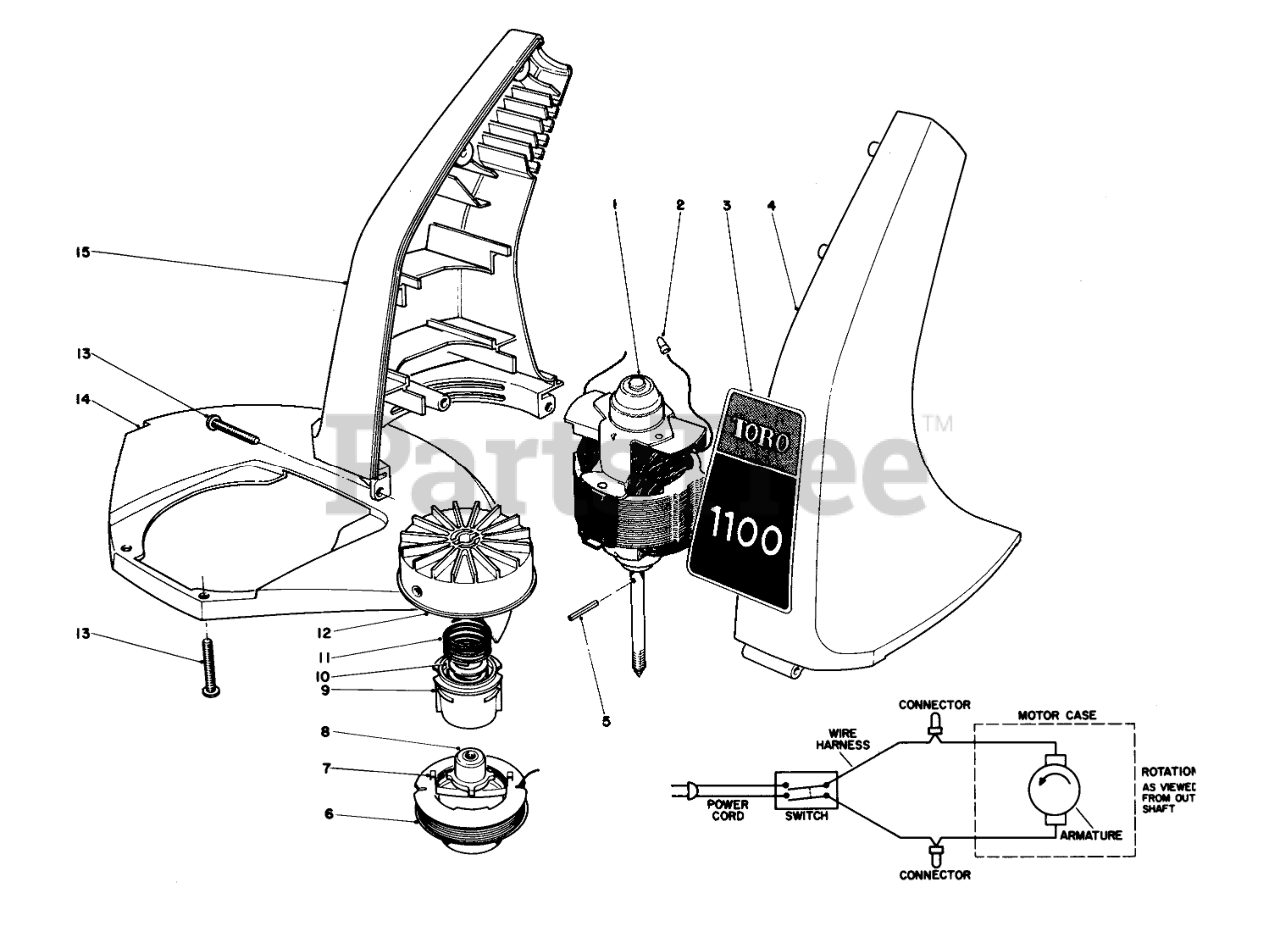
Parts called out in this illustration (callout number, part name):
1	Motor (240 V)
2	CONNECTOR WIRE JOINT
3	1100 Decal
4	Housing-Left Hand
5	COIL PIN
6	Prewound Spool
7	SADDLE-SPOOL CAP
8	Driver
9	SPOOL CORE
10	Washer
11	SPRING COMPRESSION
12	DRUM W/EYELET
13	Screw
14	Shield
15	HOUSING-RH-INT'L
